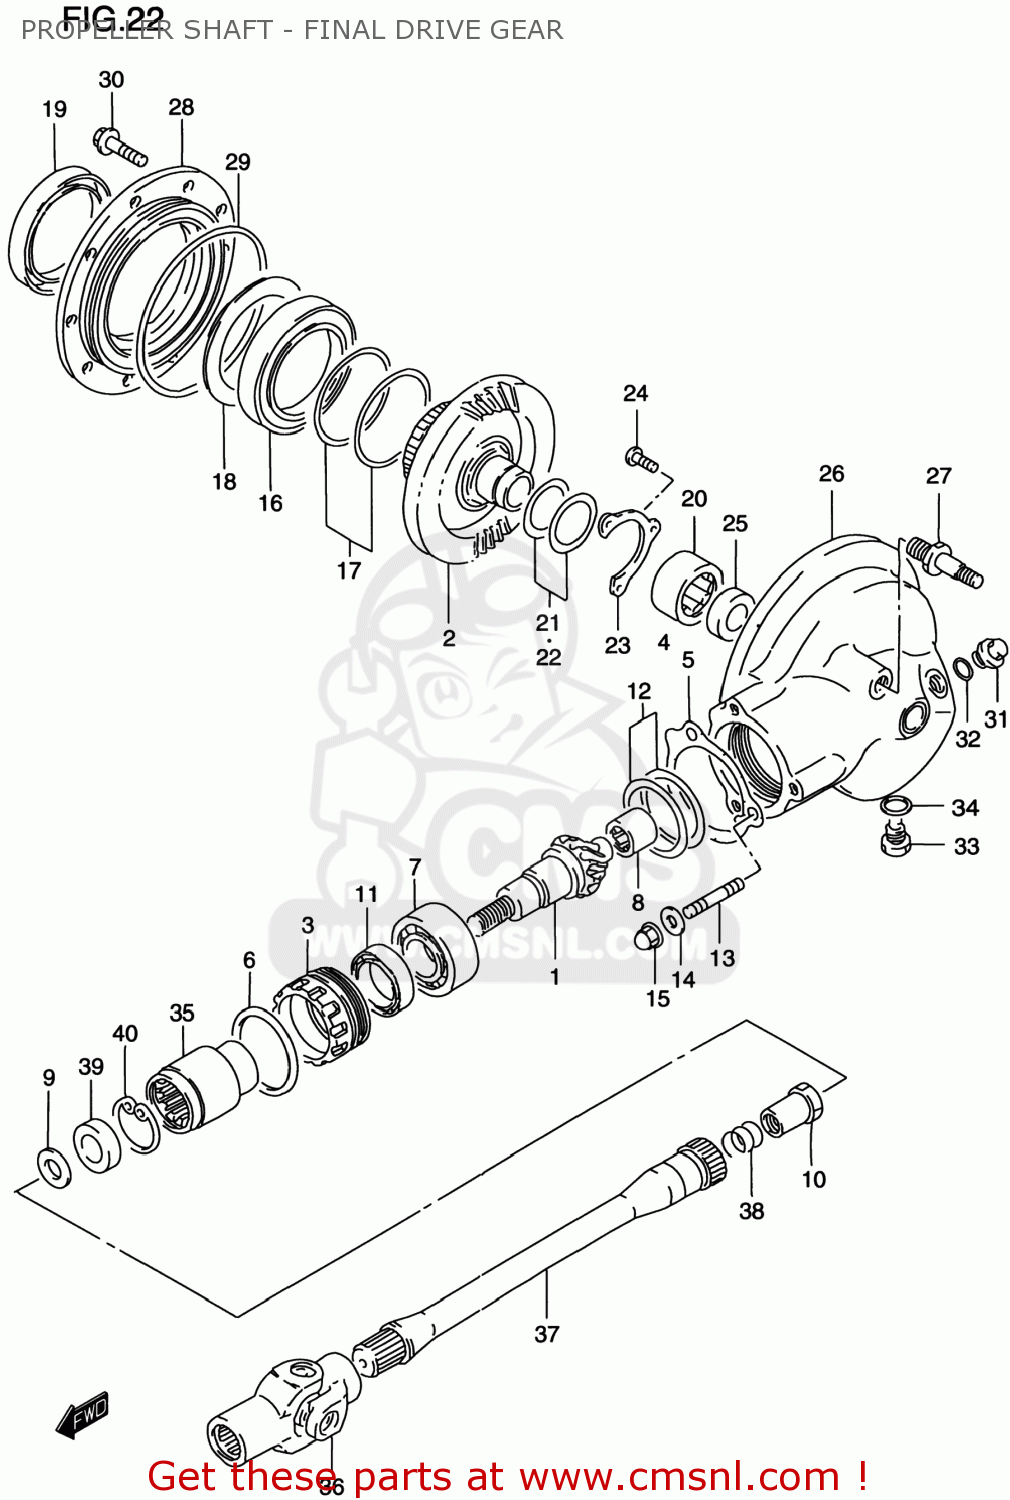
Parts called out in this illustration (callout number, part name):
1	GEAR,FINAL DRIVE BEVEL(NT:11)
2	GEAR,FINAL DRIVEN BEVEL(NT:34)
3	STOPPER,FINAL DRIVE BEARING
4	PLATE,BEARING STOPPER
5	PLATE,BEARING STOPPER
6	O RING(D:1.9,ID:61.6)
7	BEARING(30X62X23.8)
8	BEARING(17X32X16)
9	WASHER(16X29X4)
10	NUT
11	SEAL,OIL(38X54X6)
12	SHIM SET,FINAL DRIVE GEAR
13	BOLT,STUD
14	WASHER
15	NUT
16	BEARING(70X110X13)
17	SHIM SET,DRIVEN GEAR BEARING
18	PLATE,FINAL DRIVEN BRG OIL
19	SEAL,OIL(70X96X16)
20	BEARING(32X46X17.7)
21	SHIM SET,FINAL DRIVEN GEAR
22	SHIM SET,FINAL DRIVE GEAR
23	RETAINER,FINAL DRIVEN GEAR BRG
24	SCREW
25	SEAL,OIL(30X42X7)
26	CASE,FINAL
27	BOLT,STUD
28	CASE,FINAL GEAR BEARING
29	O RING(D:3.5,ID:131.6)
30	BOLT
31	PLUG
32	O RING(D:2.4,ID:17.8)
33	PLUG
34	GASKET(13.8X18.8X4.8) (NAS)
35	COUPLING,FINAL DRIVE GEAR
36	YOKE COMP,UNIVERSAL JOINT
37	SHAFT,PROPELLER
38	SPRING
39	SEAL,OIL(28.4X48X15)
40	CIRCLIP
